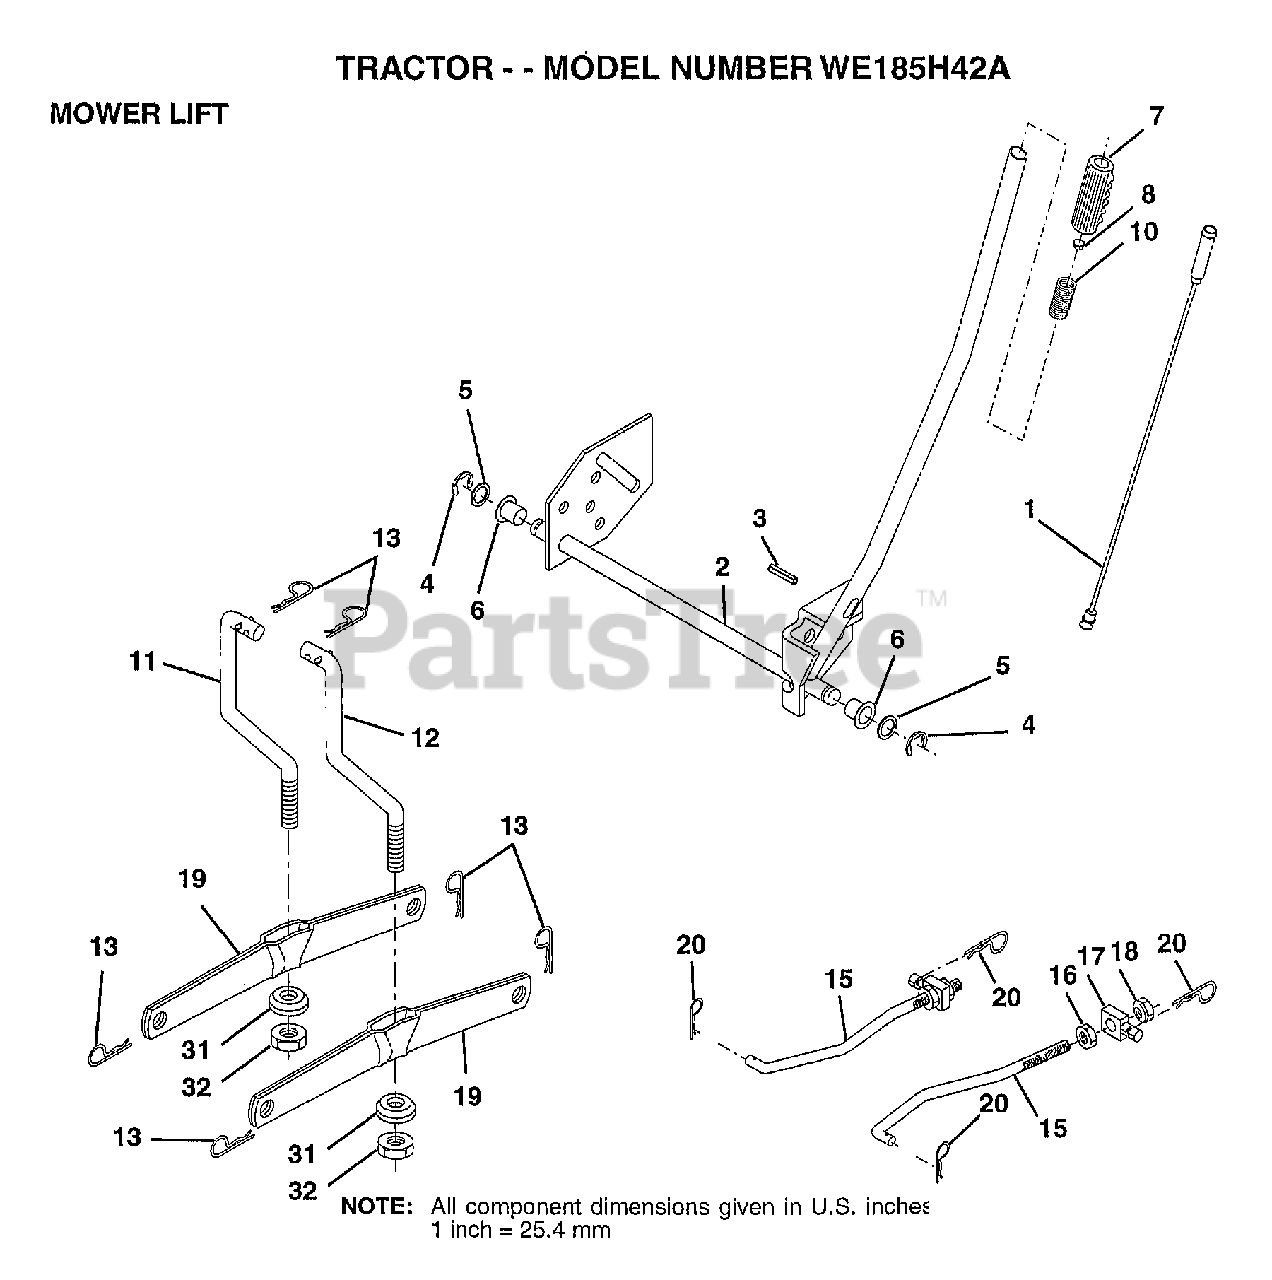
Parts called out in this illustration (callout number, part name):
1	WIRE ASM
2	SHAFT.LIFT.ASM.RH
3	PIN-GROOVE LT
5	WASHER
6	NYLON BEARING
7	GRIP
15	LINK.FRONT
16	NUT
17	TRUNION
18	NUT.LK.W/WSH.1/2.
19	ARM SUSP REAR
20	RETAINER.SPRING
31	BEARING PVT LH
32	NUT.CROWNLOCK.3/8
